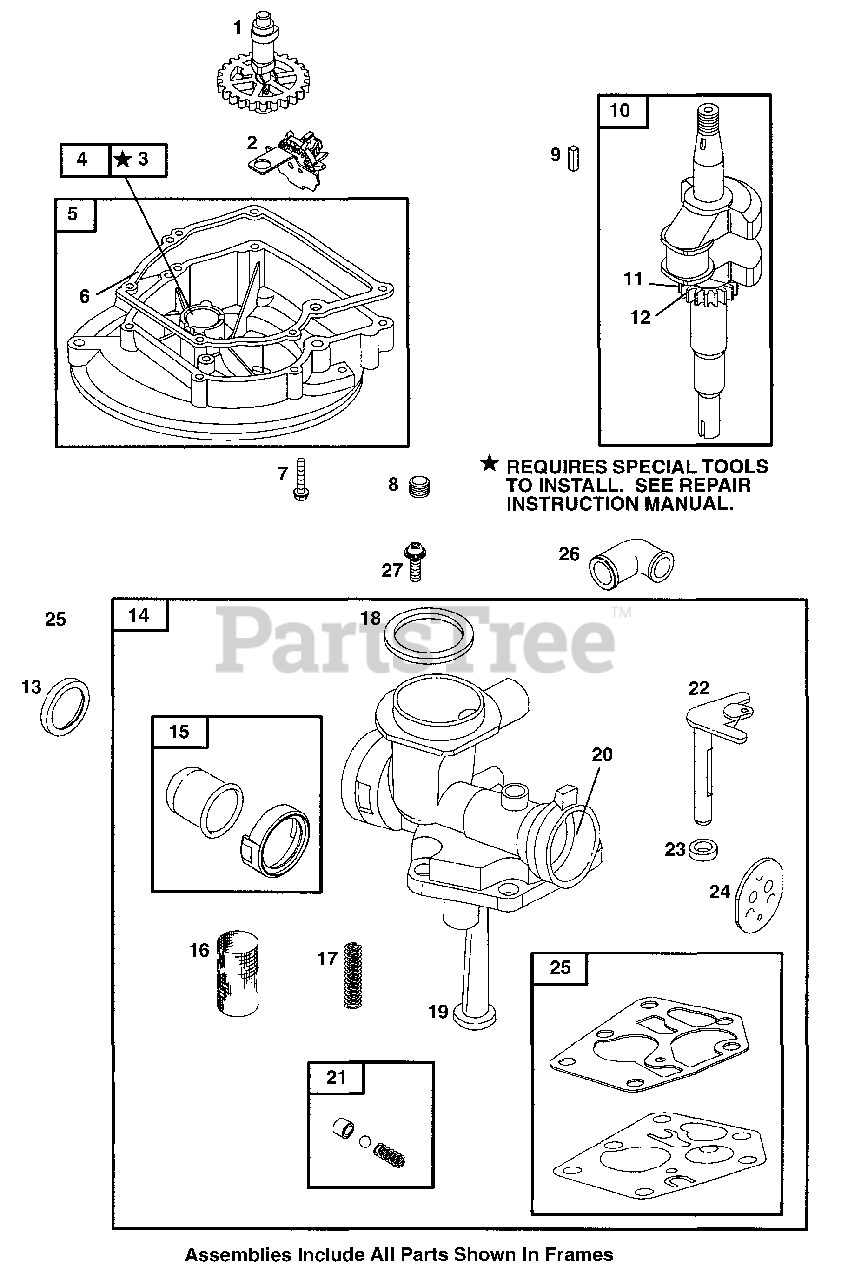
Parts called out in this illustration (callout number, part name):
1	Cam Gear (Clockwise)
2	Oil Slinger/Governor
4	Oil Seal
5	Engine Sump
6	Crankcase Gasket (Standard)
7	Hex Screw
8	Oil Drain Plug
9	Flywheel Key
10	Crankshaft
11	Timing Key
12	Timing Gear
13	Trim Ring (Primer Bulb)
14	Carburetor
15	Carburetor Primer
16	Carburetor Screen
17	Choke Diaphragm Spring
18	Air Cleaner Gasket
19	Pickup Tube
20	Intake Manifold Seal
21	Check Valve Seat
22	Throttle Shaft
24	Throttle Valve
25	Carburetor Diaphragm
26	Grommet
27	Screw Phillips
